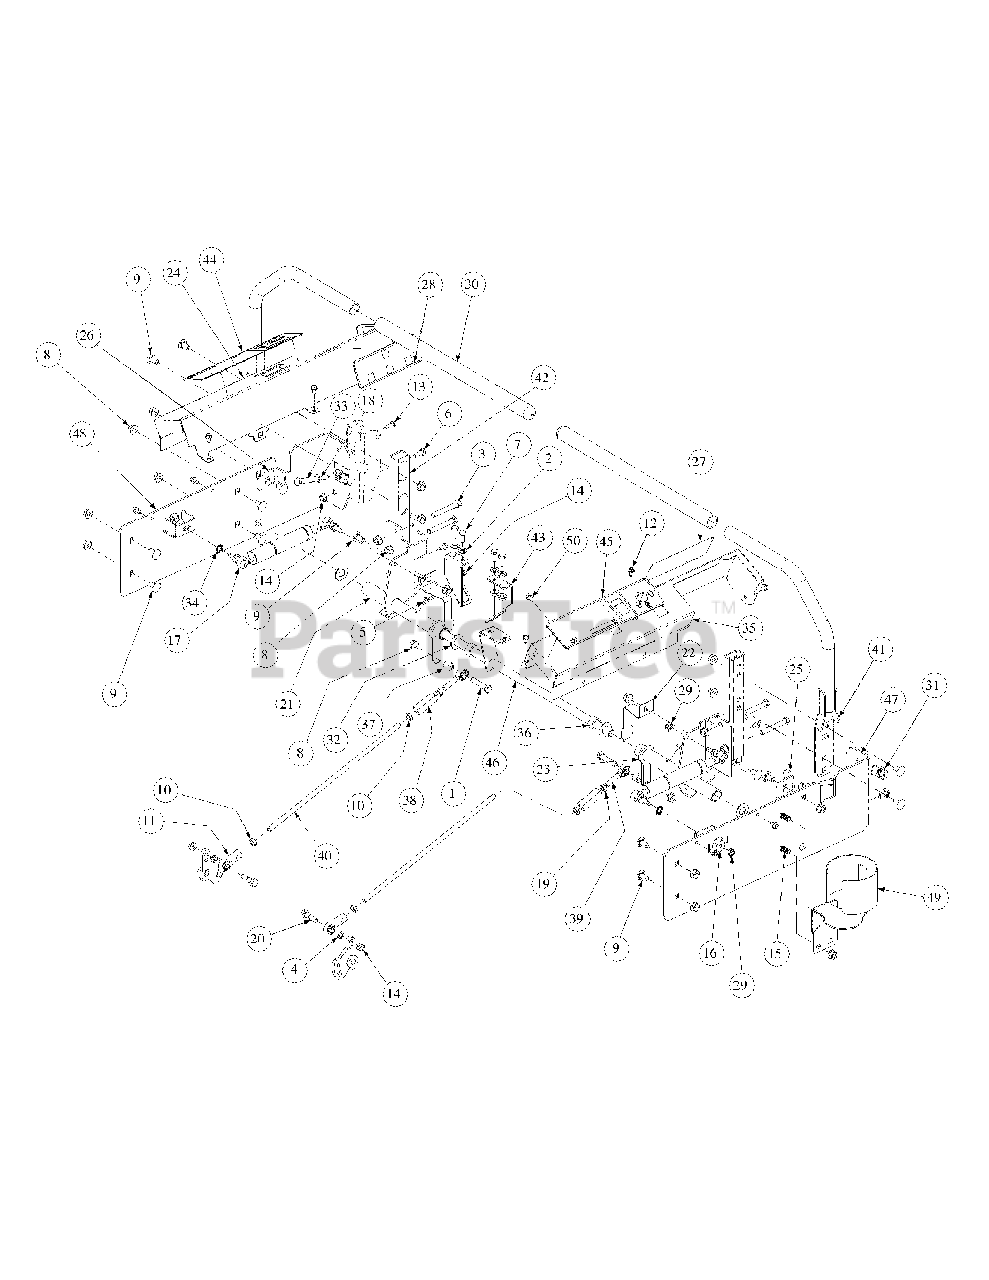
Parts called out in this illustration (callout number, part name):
1	Capscrew, 3/8-16 x 1-3/4
2	Flat Washer, 5/16
3	HHCS, 3/8-16, 2.25
4	5/16, Lock Washer
5	Grease Fitting, 90 degree
6	HHCS, 5/16-18 x 1.0
7	Hex, Cap Screw, 5/16-18 x 3/4
8	Hex Nut, 3/8-16, Lock Flange
9	Carriage Bolt, 3/8-16 x .75
10	Hex Jam Nut, 3/8-24
11	B/Joint, 3/8-24, Right Hand Female
12	Screw, TT, 1/4-20, 0.5, Hex Index Washer
13	Screw, TT, 1/4-20, 0.75, Hex Index Washer
14	Nut, Lock, Hex Flange, 5/16-18
15	Carriage Bolt, 3/8-16 x 1
16	Belle Washer, .325 x .930 x .045
17	Cylinder Return to Neutral
18	Nut, 3/8-16, Jam
19	Nut, 3/8-24, Jam, LH Third
20	Screw, Shoulder Control Rod
21	Hub Assy, Control LH Bearing
22	Lever, Safety Switch
23	Hub Assy, Control RH Bearing
24	Control Panel, LH
27	Decal Right Hand Control
28	Decal, Left Hand Control
29	Nut, Hex, Center Lock, M8
30	Grip, 1.0
31	U-Nut, 3/8-16, .75
32	Flat Washer, 5/8 Nylon
33	HHCS, 3/8-16, 3.00
34	External Washer, 3/8
35	Control Panel, RH
36	Shaft Collar
37	Spacer, .385ID x .625 OD x .50 Lg
38	Turnbuckle
39	B/Joint, 3/8-24, Left Hand Female
40	Rod Connector 3/8 OD x 14.25
41	Lapbar, Handle Assembly
42	Mounting Handle
43	Switch Mounting Bracket, Lapbar
44	Decal, Left Hand Console
45	Decal , Right Hand Console
46	Shaft Control Brake Steering
47	Side Panel, Control, Right
48	Side Panel, Control, Left
49	Cup Holder Assembly
50	Screw Button Head, 1/4-20 x .5
